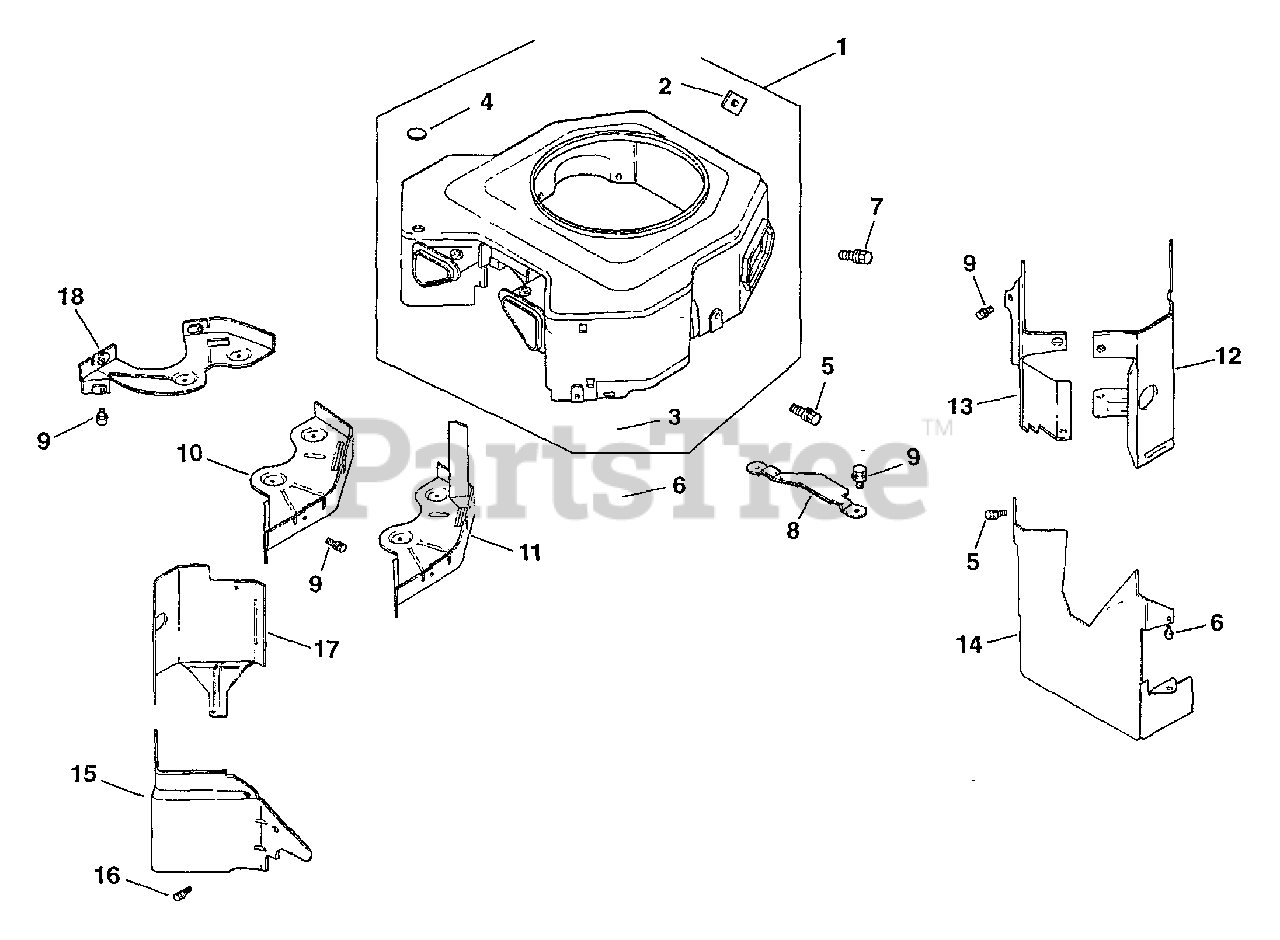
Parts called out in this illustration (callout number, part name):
1	KIT, BLOWER HOUSING (SERVICE) USE 24 027 449-S
2	NUT, PLASTIC (KM)-USE 25 100 37-S
3	NUT, PLASTIC
4	PLUG, BUTTON 9/16
5	SCREW - USE M-545016
6	Screw, hex. flange M5x0.8x20
7	Screw, hex. flange M5x0.8x16
8	BRACKET - USE 24 126 71
9	SCREW - USE M-645016
15	BAFFLE, VALLEY #2 SIDE-USE 24 063 94-S
16	SCREW - USE M-545010
18	PLATE, BACKING NO. 1 SIDE - USE 24 146 20
